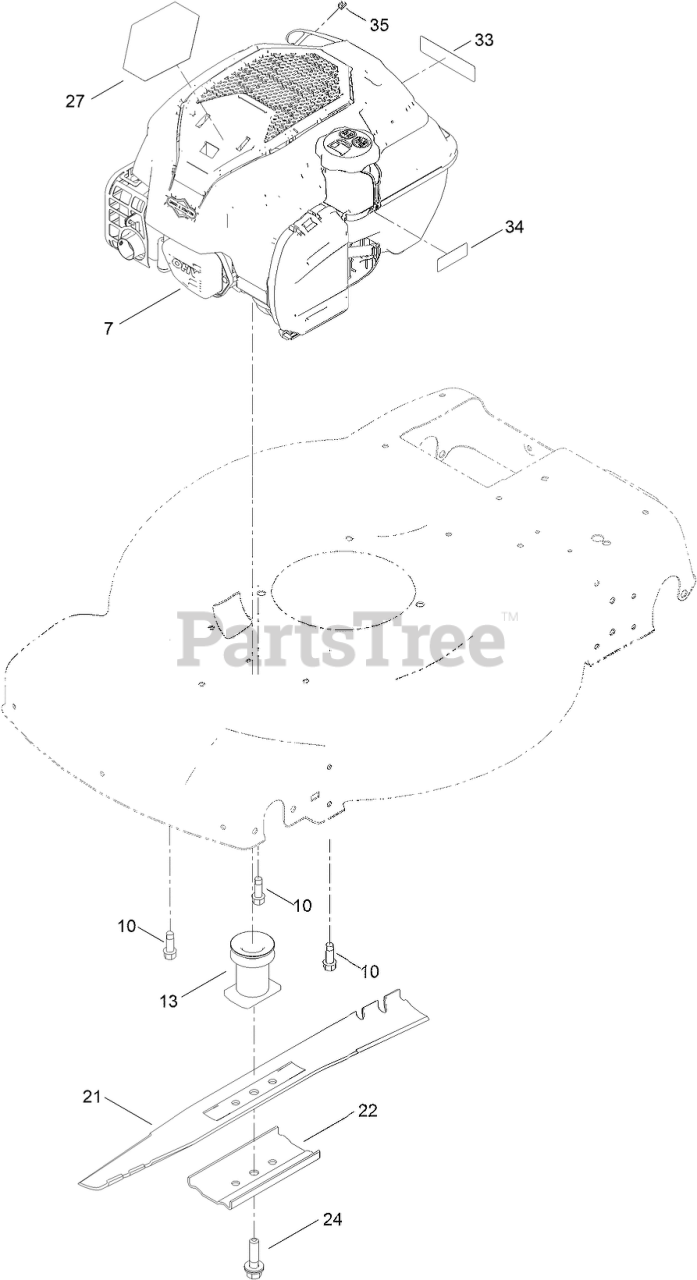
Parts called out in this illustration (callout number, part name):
10	SCREW-THD FORM, HWH
13	DRIVER-BLADE
22	SUPPORT-BLADE
24	BOLT-BLADE
27	DECAL - BRIGGS 675 EXI SS
33	DECAL-ARRESTOR, SPARK
34	DECAL-LEVEL, FUEL
35	STOP-ROPE
